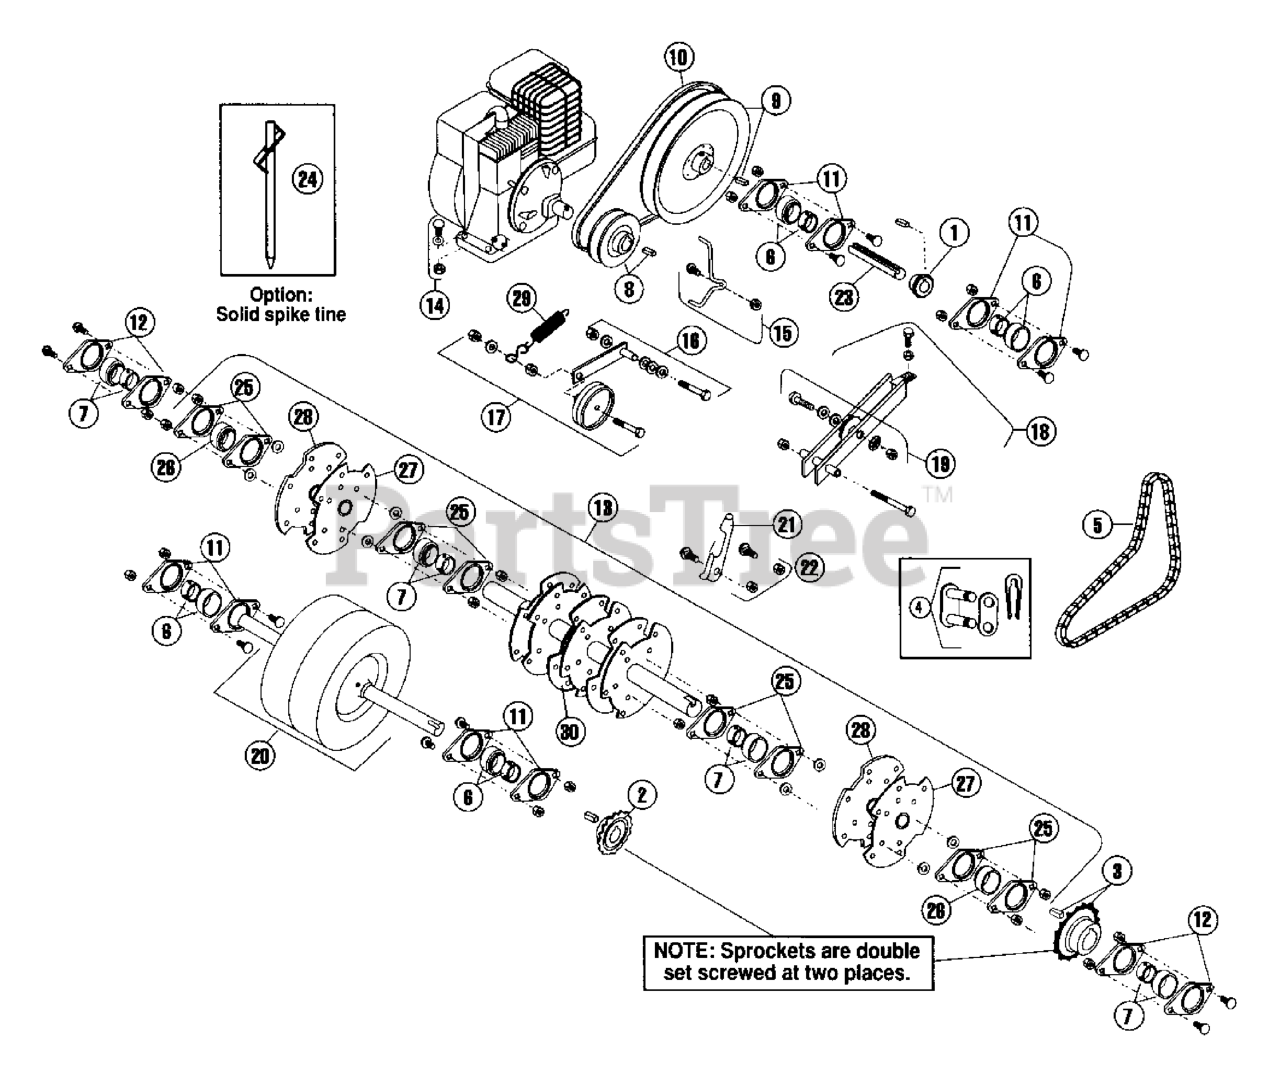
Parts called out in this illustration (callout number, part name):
1	SPROCKET/JACKSHAFT W/SPACER
2	SPROCKET W/KEY, WHEEL
3	SPROCKET
4	CHAIN LINK #40
5	CHAIN #40
6	BEARING
7	BEARING 1"
8	V-PULLEY, A-4"X3/4" BORE W/KEY
9	V-PULLEY
10	ENGINE BELT - V
11	STAMPING KIT
12	STAMPING KIT
13	ROTOR SHAFT
14	FASTENER KIT
15	BELT KEEPER KIT
16	IDLER ARM KIT
17	IDLER PULLEY KIT
18	IDLER ARM KIT W/SPROCKET
19	IDLER SPROCKET KIT
20	FRONT WHEEL
21	TINE SET - 30 EACH
21	TINE SET
22	TINE/SPIKE FASTENER KIT
22	BOLT KIT
23	JACK SHAFT
25	STAMPING KIT
26	BEARING
27	LEFT ROTOR PLATE
28	RIGHT ROTOR PLATE
29	SPRING
30	ROTOR SHAFT
